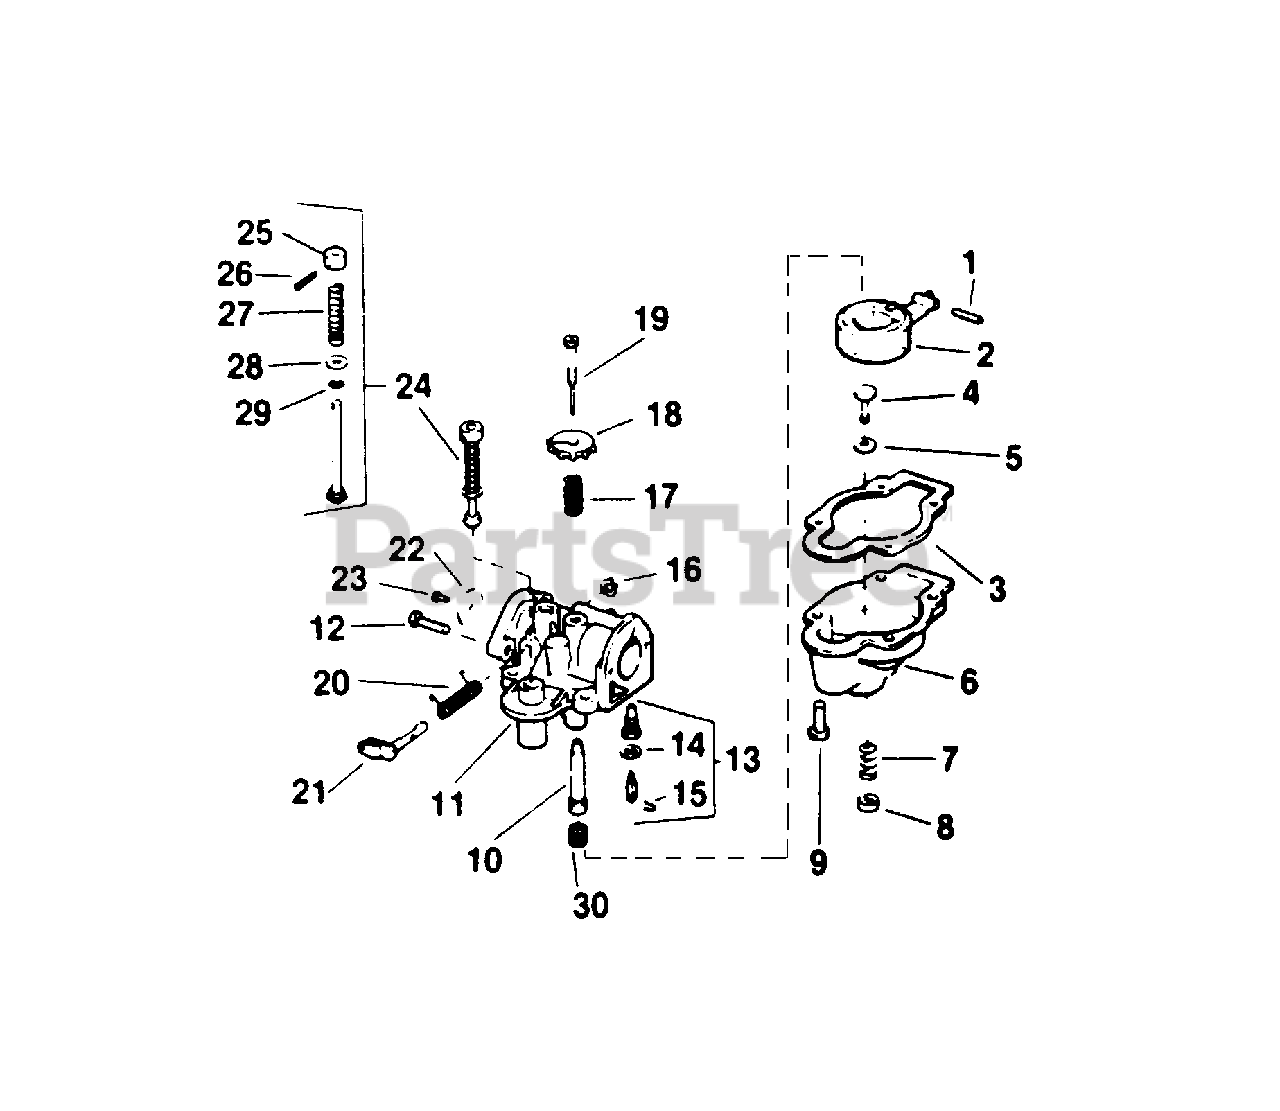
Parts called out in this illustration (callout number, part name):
1	Pin-Float Arm Hinge
2	Float and Arm Assy.
3	Gasket-Float Chamber
4	Valve Stem
5	Valve Seat
6	Chamber-Float
7	Valve Spring
8	Valve Keeper
9	Screw-Float Chamber
10	Nozzle
11	Carburetor Body Assy.
13	Float Valve & Seat
14	Washer-Float Valve Seat
15	Clip
16	Grip Ring
17	Spring-Needle Adj.
18	Knob-Needle Adj.
19	Needle Assy.
20	Spring-Throttle
21	Throttle Shaft & Lever Assy.
22	Disc-Throttle
23	Screw-Throttle Shaft Disc
24	Primer Assy.
25	Knob Primer
26	Cotter Pin
27	Spring Compression
28	Washer-Plain
29	"O" Ring
